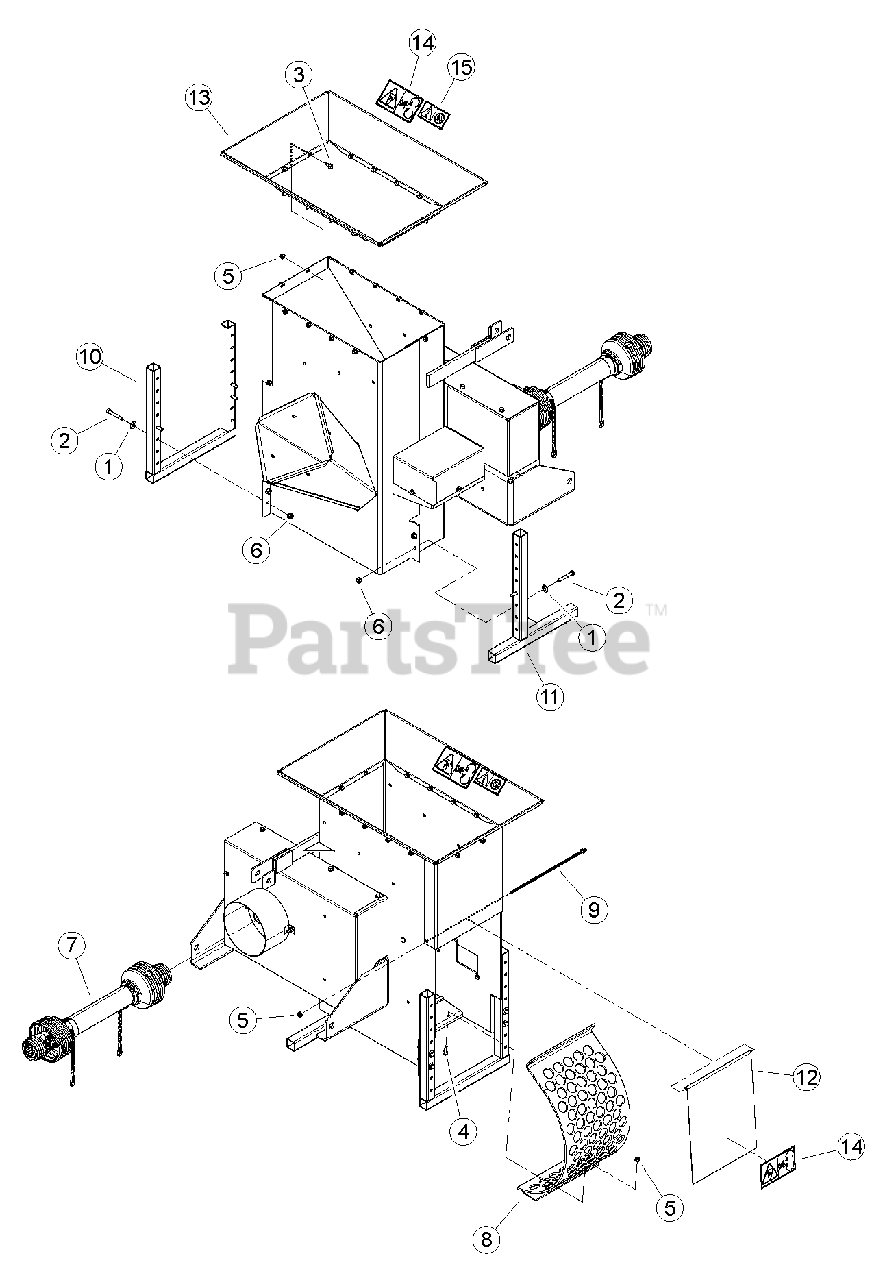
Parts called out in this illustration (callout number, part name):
1	WASHER, 3/8" FLAT ZP
2	BOLT, 3/8 X 2-1/2 GR5 HHCS ZP
3	BOLT, 5/16 X 3/4" SERRATED FLANGE NF
4	BOLT, 5/16 X 1 FLANGE NC
5	NUT, 5/16-18 NYLOCK FLANGE
6	NUT, 3/8-16 NYLOCK FLANGE
7	DRIVELINE, 22.0/30.4" 1-3/8 SPL
8	WELDMENT, LARGE SCREEN COARSE
9	ROD, DOOR PIVOT
10	WELDMENT, PTO C/S STAND
11	WELDMENT, PTO C/S POST
12	DOOR, DISCHARGE WITH DECAL
13	ASSEMBLY, HOPPER W/ DECALS
14	DECAL, BLADE DANGER ISO
15	DECAL, SHREDDER SIZE ISO
